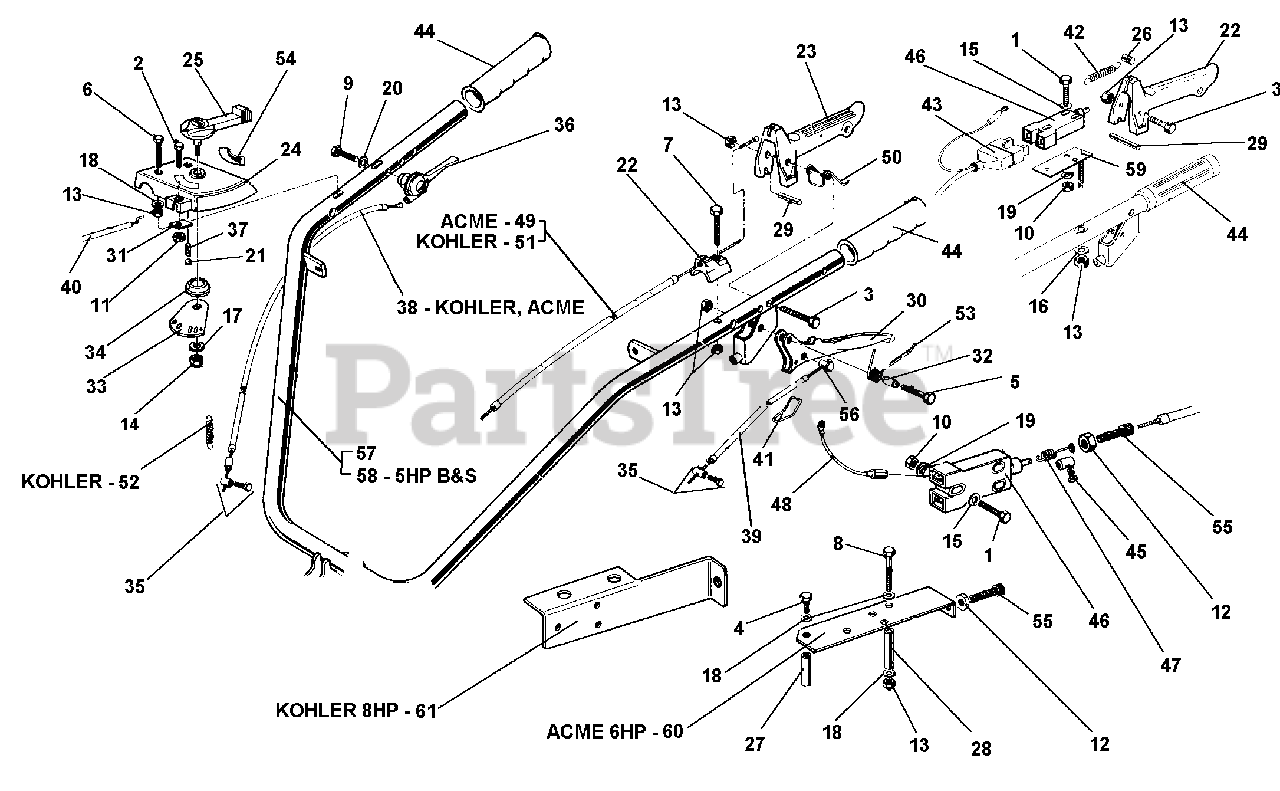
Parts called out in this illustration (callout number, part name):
1	SCREW TE M4 X 25
2	SCREW M5 X 10
3	SCREW TE M6 X 45
4	SCREW M6 X 12
5	SCREW M6 X 25
6	SCREW M6 X 40
7	SCREW M6 X 35
9	SCREW TE M8 X 40
13	NUT, SELF LOCKING M6
14	NUT, SELF LOCKING M8
15	FLAT WASHER 4.3
16	FLAT WASHER 6.4 X12.5
17	FLAT WASHER 13
18	LOCK WASHER 6.4
19	LOCK WASHER 4.3
20	LOCK WASHER 8.4
21	BALL 1/4 RIV RB 6.35
22	CABLE STOP OF MOTOR STOP
23	MOTOR STOP LEVER
25	THROTTLE LEVER
28	PROTECTION SPACER
29	LEVER STOP FOR MOTOR STOP
30	CLUTCH LEVER
32	LEVER SPACER
33	THROTTLE LEVER
35	CLAMP, CABLE
36	LEVER, ACCELERATOR
38	THROTTLE CABLE, 715
39	CLUTCH CABLE
40	THROTTLE CABLE, B&S
42	MOTOR STOP SPRING
43	MOTOR STOP CABLE, B&S
45	CABLE CLAMP
46	STOP SWITCH
47	SWITCH SPRING
48	SWITCH CABLES
49	THROTTLE CABLE, ACME
50	MOTOR STOP LEVER SPRING
51	THROTTLE CABLE, 715 KOHLER
52	SPRING, KOHLER THROTTLE
53	LEVER SPRING
54	GAS DECAL FOR ENGINE
55	ADJUSTING SCREW
59	STOP SWITCH SUPPORT
60	SWITCH SUPPORT, ACME
61	SWITCH SUPPORT, KOHLER
